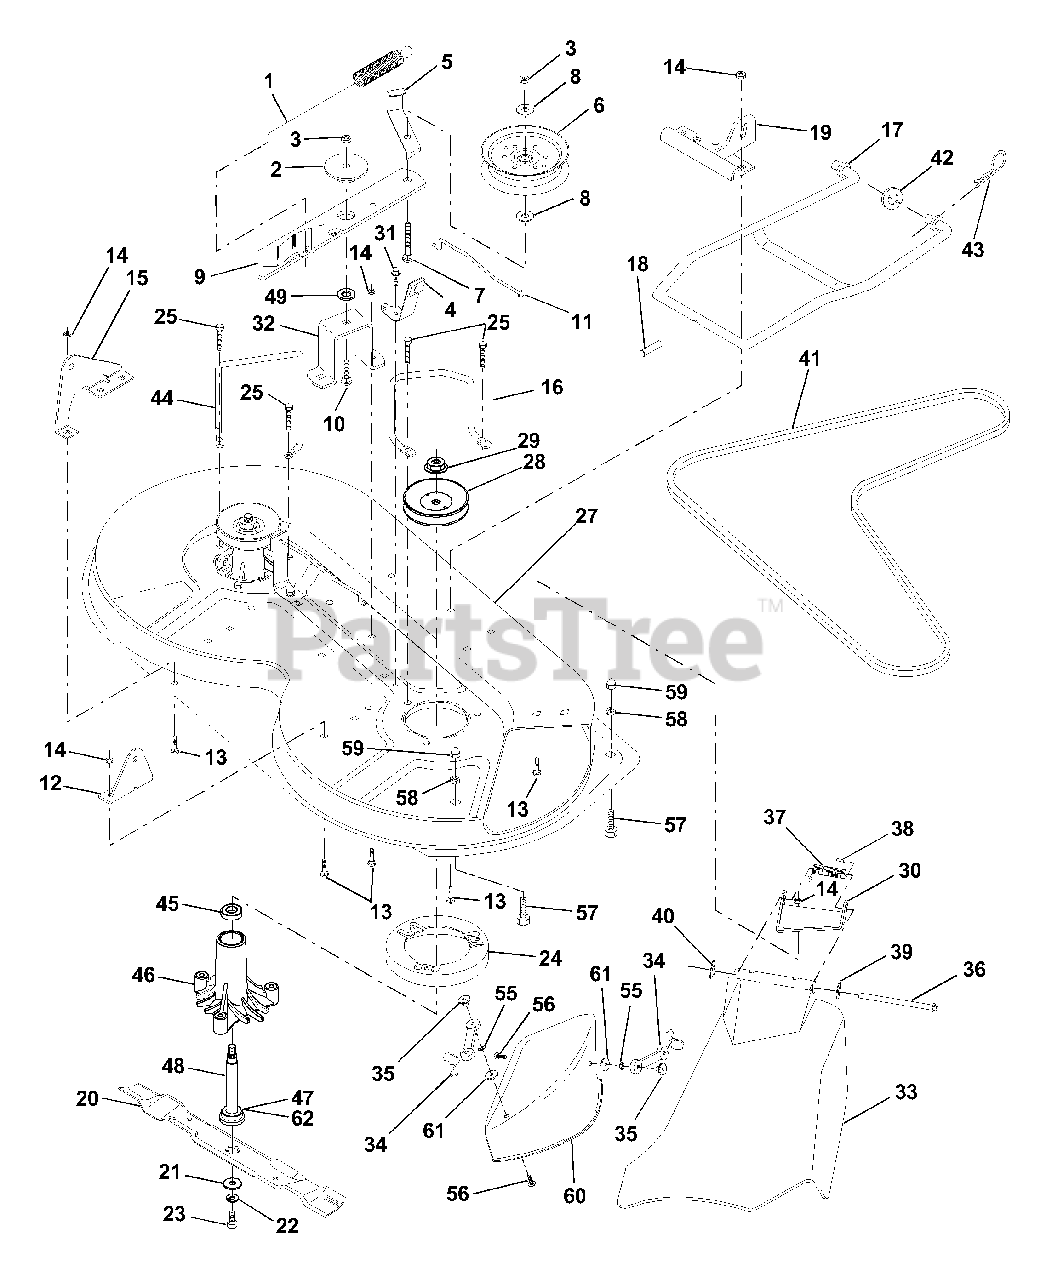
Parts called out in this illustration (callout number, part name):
1	Spring, Mower Clutch
2	Spacer, Retainer
3	Nut, Crownlock 3/8-16
4	Brake Asm.
5	Guide, Belt Idler
6	Pulley, Flat Idler
7	Bolt, Carr. 3/8-16 x 1-3/4 Gr. 5
8	Washer 13/21 x 7/8 x 10 Ga.
9	Arm Asm., Idler Mower
10	Bolt, Carriage 3/8-16 x 1-1/4
11	Rod, Brake
12	Bracket, Lift R. H. Rear
13	Bolt, Carriage 5/16-18 x 3/4
14	Nut, Crownlock 5/16-18
15	Bracket, Lift L. H. Rear
16	Keeper, R. H.
17	Link, Asm. Mower Stabilizer
18	Pin, Drive
19	Bracket, Asm. Front
20	Blade Mulching
21	Washer, Hard
22	Washer, Lock 3/8
23	Bolt 3/8-24 x 1-1/4 Gr. 8
24	Stripper
25	Screw Thdrol Wsh Hd
27	Deck Assembly
28	Pulley, Mandrel
29	Nut, Flangelock 9/16
30	Bracket, Asm. Deflector
31	Screw, Hex Wsh. Thdrol. 5/16-18 x 1/2
32	Arm, Support Idler Mower
33	Deflector
34	Latch Asm, Bagger/Mulch
35	Nut, Weld
36	Rod, Hinge
37	Spring, Torsion Deflector
38	Cap, Sleeve
39	Washer 11/32 x 5/8 x 16 Ga.
42	Washer 11/32 x 5/8 16 Ga.
43	Retainer, Spring
44	Keeper, L. H.
46	Housing Mandrel Vented
48	Shaft, Mandrel
49	Washer, Hardened
55	Washer, Lock
56	Screw
57	Bolt, Fin Hex 5/16-18 x 1
58	Nut, Lock Hex w/Ins. 5/16-18
59	Nut, Acorn Hex 5/16 x 18
60	Cover, Mulching
62	Washer Felt
